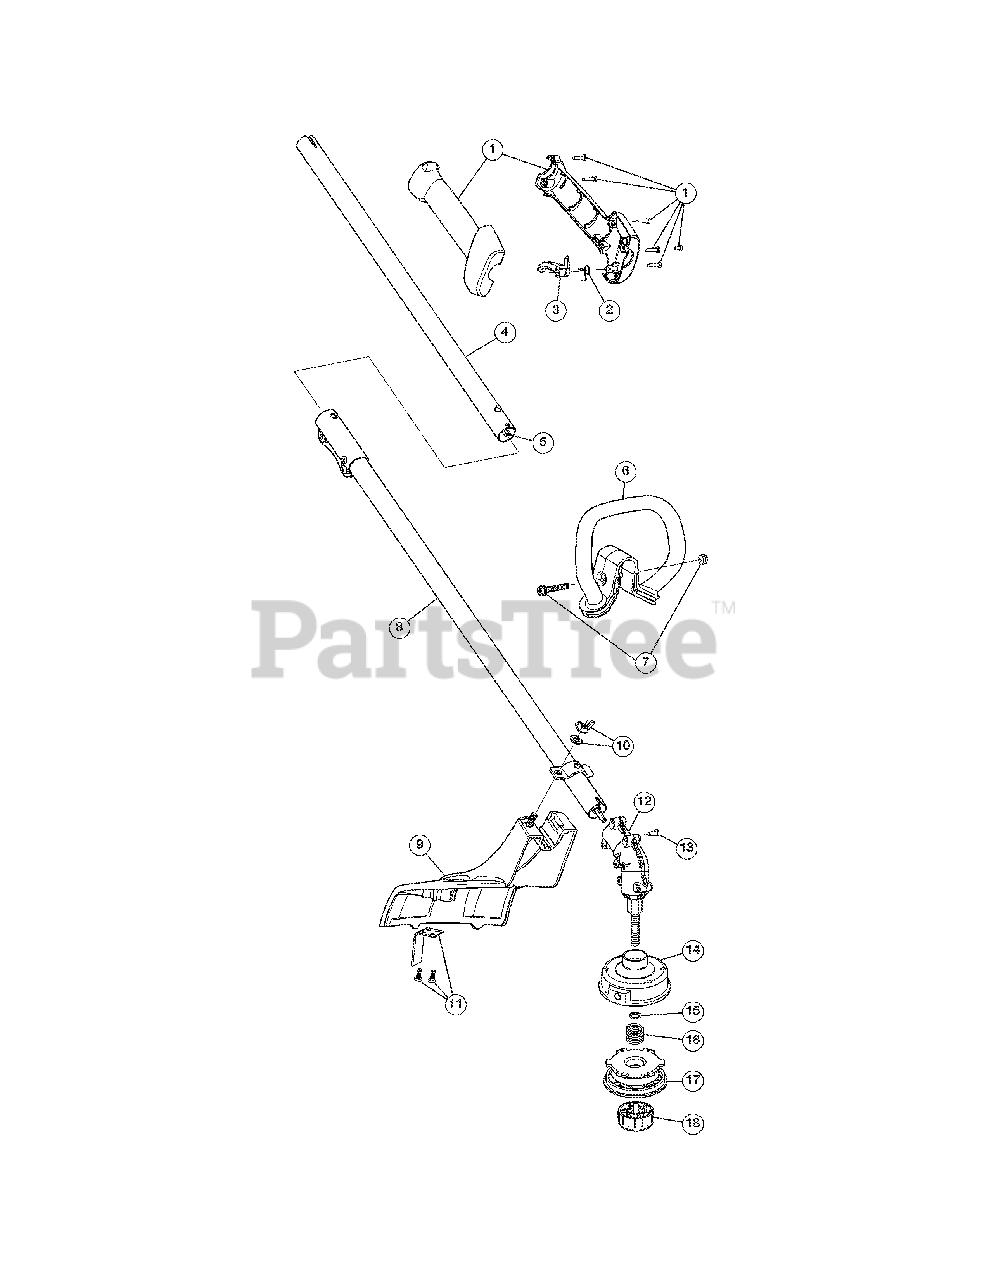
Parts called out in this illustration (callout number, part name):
1	Throttle Housing Assembly (Incl. 2 & 3)
2	Throttle Trigger Spring
3	Throttle Trigger
4	Upper Shaft Housing Assembly (Incl. 5)
5	Upper Flexible Drive Shaft
6	D-Handle (Incl. 7)
7	D-Handle Bolt
8	Lower Shaft Housing Assembly
9	Shield Assembly (Incl. 10 & 11)
10	Shield Mounting Hardware
11	Blade Assembly
12	Gearbox Assembly (Incl. 13 - 18)
13	Anti-Rotation Screw
14	Outer Spool Assembly (Incl. 15)
15	Retainer
17	Inner Reel
18	Bump Head Knob Assembly
